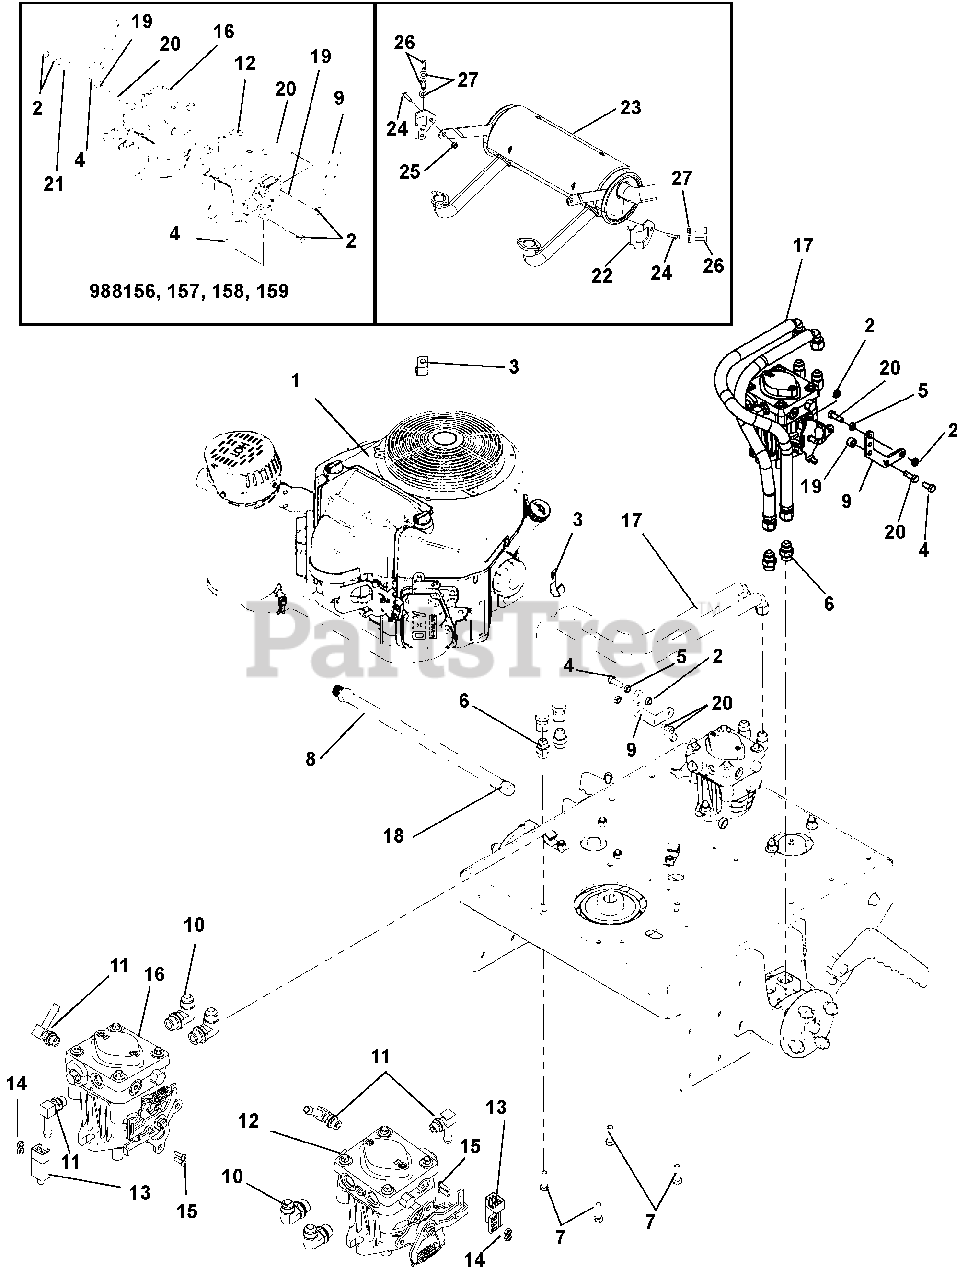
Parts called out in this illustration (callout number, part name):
1	ENGINE, KAWASAKI FS600 (988154, 155, 157, 158) (SN 000101 - 020999)
1	ENGINE, KAWASAKI FS600 (988154, 155, 157, 158) (SN 021000 and up)
1	ENGINE, KAWASAKI FS481 (988153, 156) (SN 000101 - 020999)
1	ENGINE, KAWASAKI FS481 (988153, 156) (SN 021000 and up)
1	ENGINE, KAWASAKI FS691 (988159, 169)
2	NUT, LOCKING-CENTER-JAM .31-18 (988153, 154, 155, 169)
2	NUT, LOCKING-CENTER-JAM .31-18 (988156, 157, 158, 159)
3	P-CLIP, .500 INSULATED
4	BOLT-HEX .31-18X.75 GRADE
5	NUT, JAM .312-18
6	FITTING, STRAIGHT (988153, 154, 155, 156, 157, 158)
7	BLT-HEX.38-16X1.25FTHG5 EP80YZ
8	OIL DRAIN, M20
9	BRKT-PUMP CONTROL (988153, 154, 155, 169)
10	FTG, ADP JIC-ORB 6801-08-08
11	FTG, 90 9/16 MOR X 3/8 HOSE (SN 000101 - 020000)
12	PUMP, LH HYD PE (10cc) (988153, 154, 155)
13	SWITCH, PLUNGER DP - N.O. - N.C.
14	LOCKNUT, 10-24 NYLOC Y
15	SCREW, 10-24X.625 PAN PHL MACY
16	PUMP, RH HYD PE (10cc) (988153, 154, 155, 169)
17	HOSE, HYD 1/2 X 26 1/2 EZFLEX (SN 000101 - 020000)
18	PIPE CAP 3/8 NPT FEMALE
19	BUSHING-SLV .377 x .624 x .370
20	BOLT-HEX .31-18 x 1.00 GR5
21	BRACKET, RH PS PUMP CONTROL (988156, 157, 158, 159) (SN 000101 - 020000)
22	BRACKET, EXHAUST (988159, 169) (SN 000101 - 029999)
23	EXHAUST, KAWASAKI PROSTANCE (988159, 169) (SN 000101 and up)
23	EXHAUST, KAWASAKI PROSTANCE
24	SCREW, HEX-FL M8X1.25X16 10.9
25	LOCKNUT,M8X1.25,FLANGED ZN
26	BOLT-HEX M8-1.25X20
27	WASHER-LOCKING .31X.078 REGULAR
